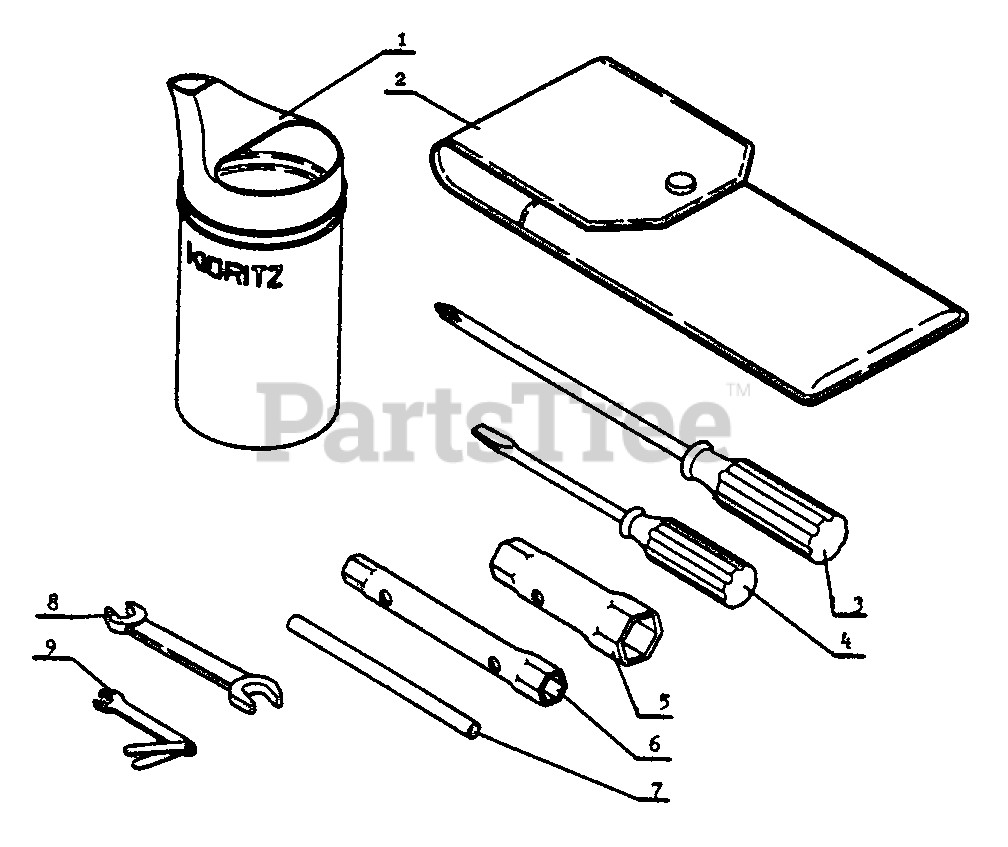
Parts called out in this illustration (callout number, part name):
1	MIXER, FUEL
2	BAG, TOOL
3	SCREWDRIVER - (+)
4	SCREWDRIVER
5	SOCKET WRENCH - 14X21mm
6	SOCKET WRENCH - 8X10mm
7	ROD, HANDLE
8	SPANNER - 8X10mm
9	Magneto spanner
